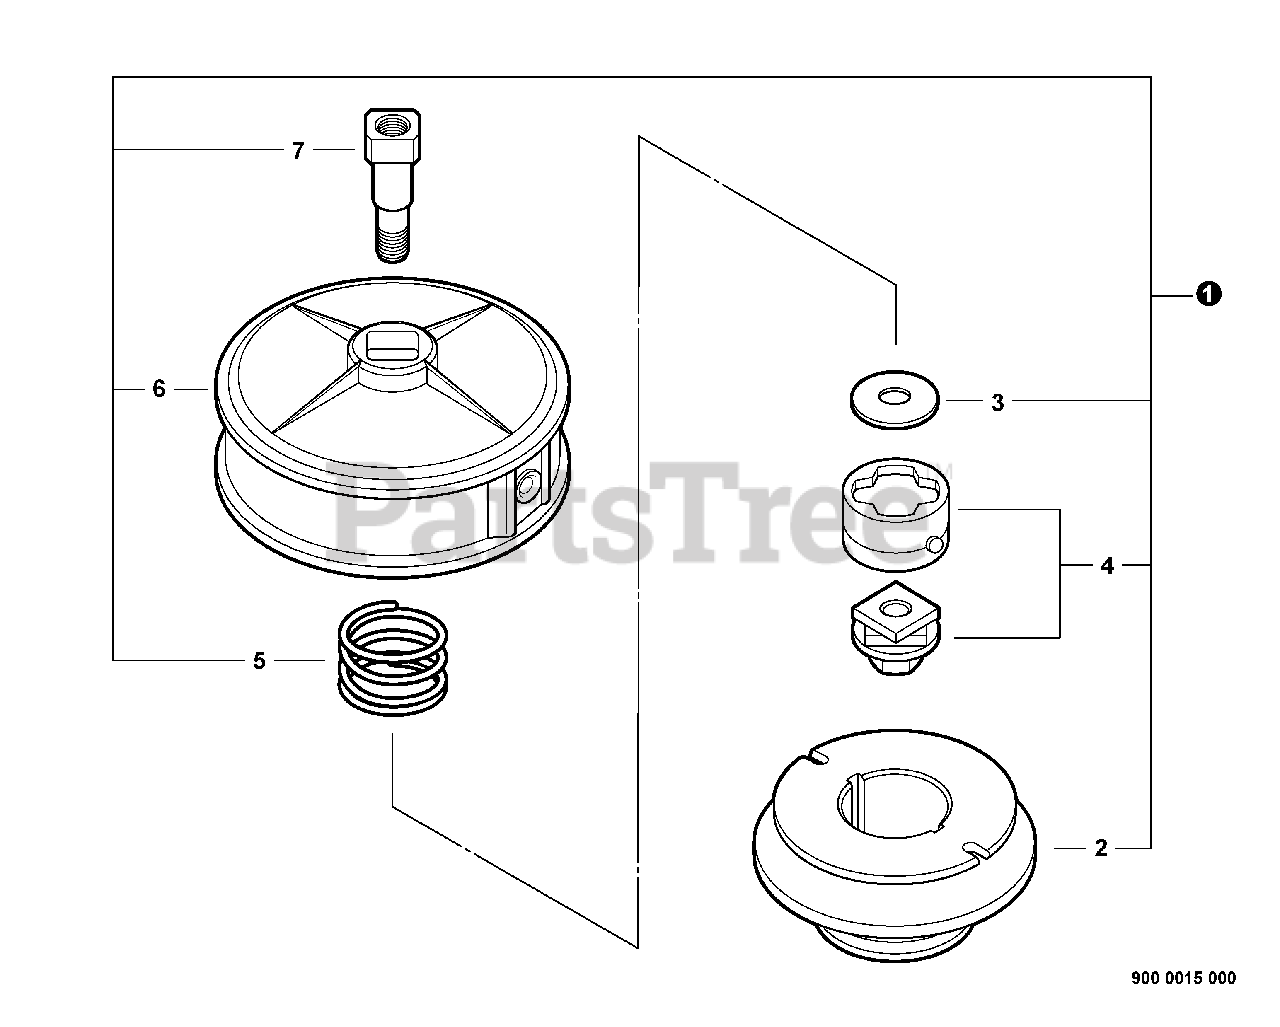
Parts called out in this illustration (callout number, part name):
1	SRM ECHOMATIC HEAD
2	SPOOL
3	WASHER
4	CAM KIT
5	SPRING
6	COVER, SPOOL
7	BOLT, SHAFT
